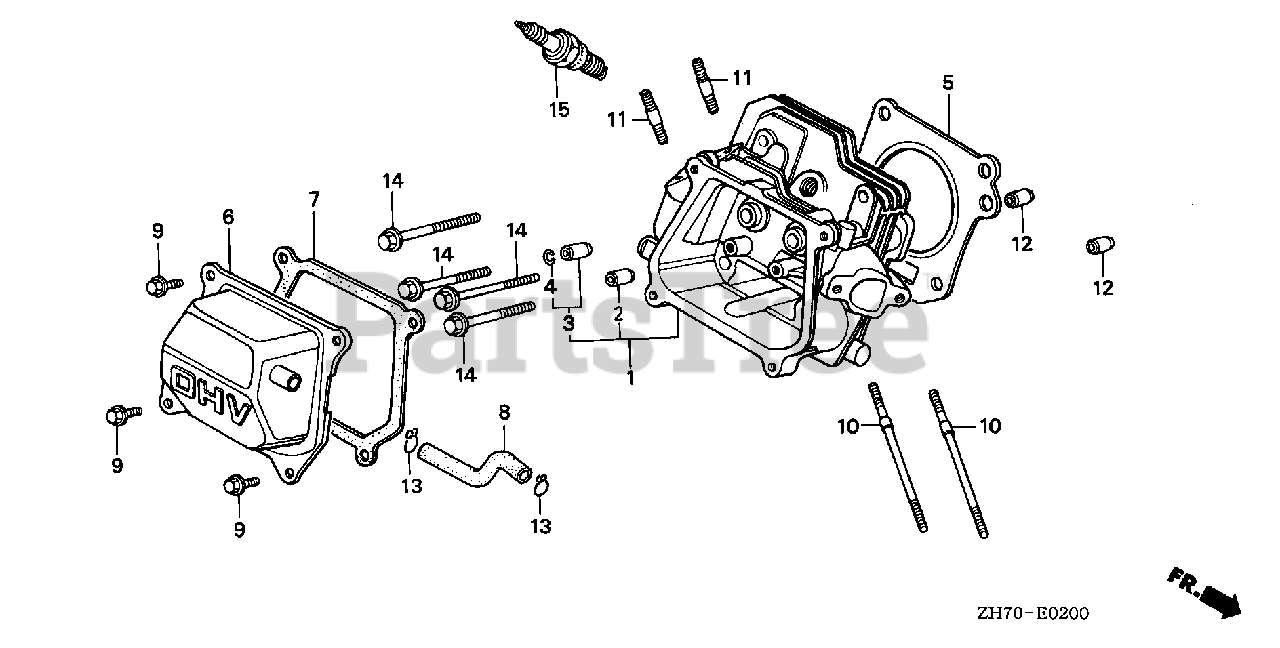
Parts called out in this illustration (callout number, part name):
1	CYLINDER HEAD
2	GUIDE, VALVE (OVER SIZE)
3	GUIDE, EX. VALVE (OVER SIZE)
4	CLIP, VALVE GUIDE
5	GASKET, CYLINDER HEAD
6	COVER, HEAD
7	GASKET, HEAD COVER
8	TUBE, BREATHER
9	BOLT, FLANGE (6X12) (CT200)
9	BOLT, FLANGE (6X13) (CT200)
10	BOLT, STUD (6X109)
10	BOLT, STUD (6X112)
11	BOLT, STUD (8X32)
12	PIN, DOWEL (10X16)
14	BOLT, FLANGE (8X55)
15	SPARK PLUG (BPR5ES) (NGK)
15	SPARK PLUG (W16EPR-U) (DENSO)
15	SPARK PLUG (BPR6ES) (NGK)
15	SPARK PLUG (W20EPR-U) (DENSO)
